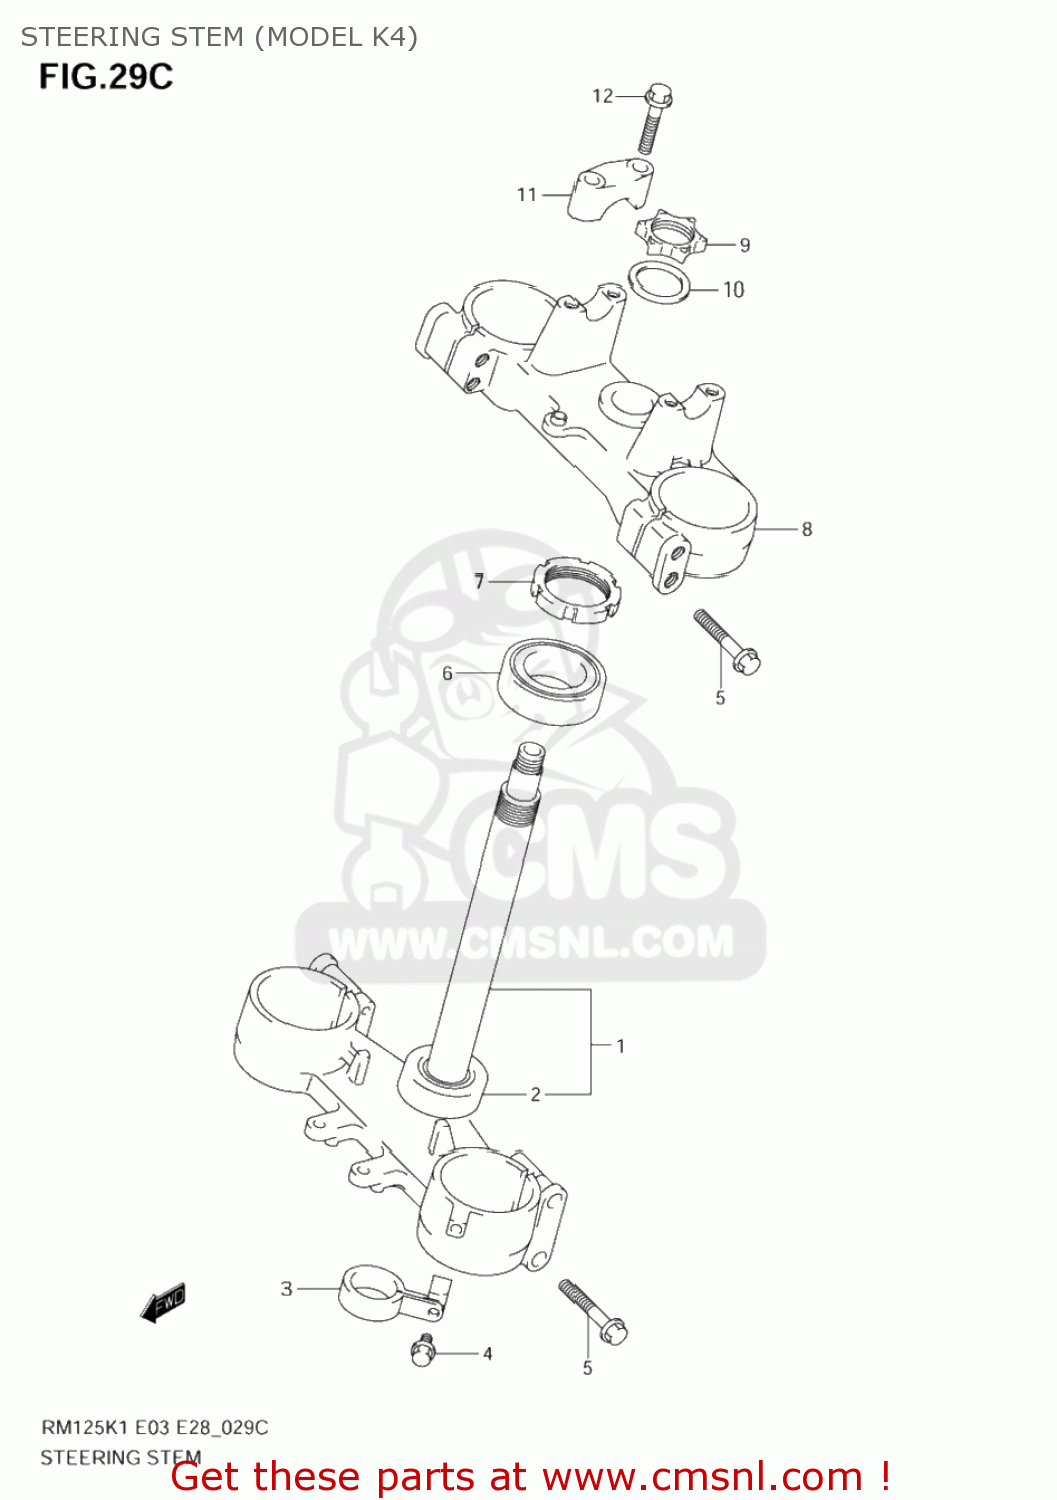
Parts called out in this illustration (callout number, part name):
1	STEM,STEERING
2	BEARING(30X52X16)
3	GUIDE,FR BRAKE HOSE
4	BOLT
5	BOLT
6	BEARING(30X52X16)
7	NUT,STEERING
8	HEAD,STEERING STEM
9	NUT,STEM HEAD
10	WASHER,STEM HEAD
11	HOLDER,HANDLE
12	BOLT
